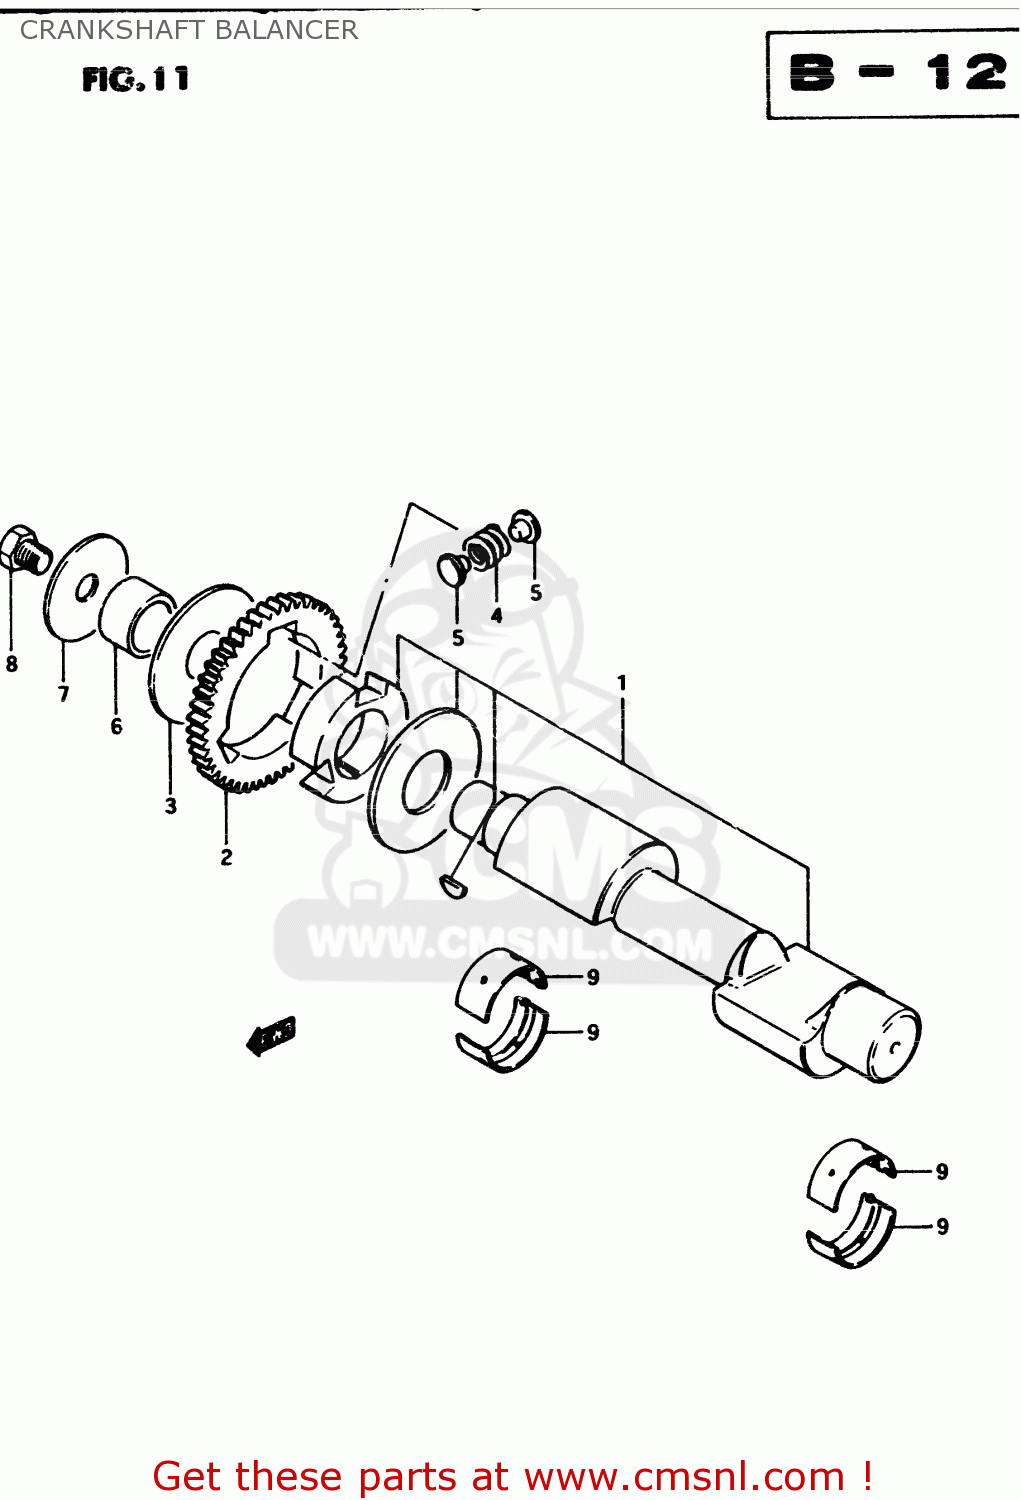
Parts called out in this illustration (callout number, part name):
1	BALANCER,CRANKSHAFT
2	GEAR,CRANK BALANCER DRIVE
3	WASHER
4	SPRING
5	PIN
6	SPACER
7	WASHER(12X50X3)
8	BOLT
9	METAL CRANKSHAFT
